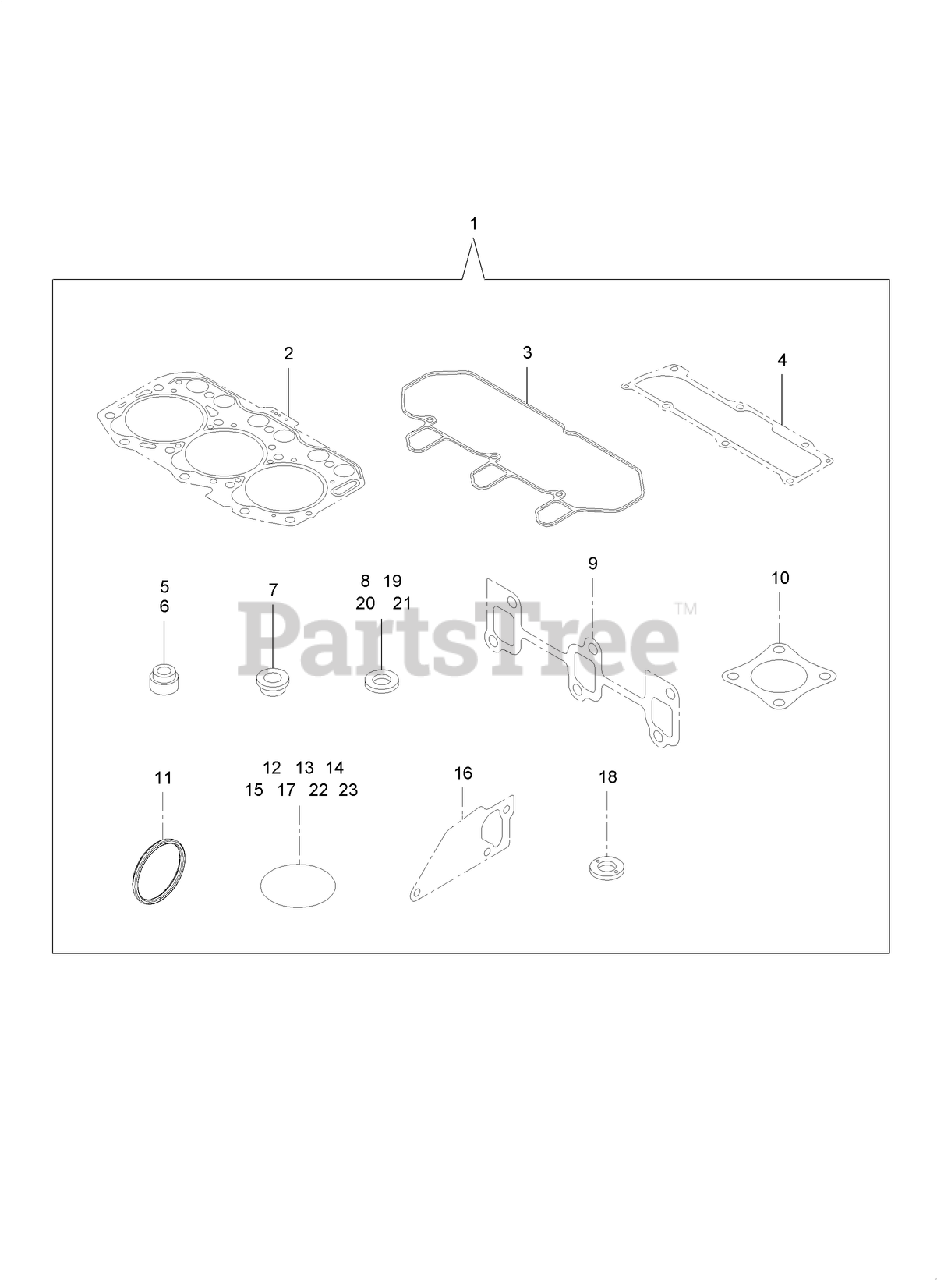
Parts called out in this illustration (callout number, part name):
1	GASKET KIT
2	GASKET SET-HEAD
3	GASKET-BONNET
5	SEAL-STEM, VALVE
6	SEAL-STEM, VALVE
7	PROTECTOR-NOZZLE
8	GASKET-NOZZLE
9	GASKET-EXH MANIFOLD
10	GASKET-SILENCER
11	GASKET-WASHER
16	GASKET-WATER PUMP
19	WASHER-SEAL
20	WASHER-SEAL
